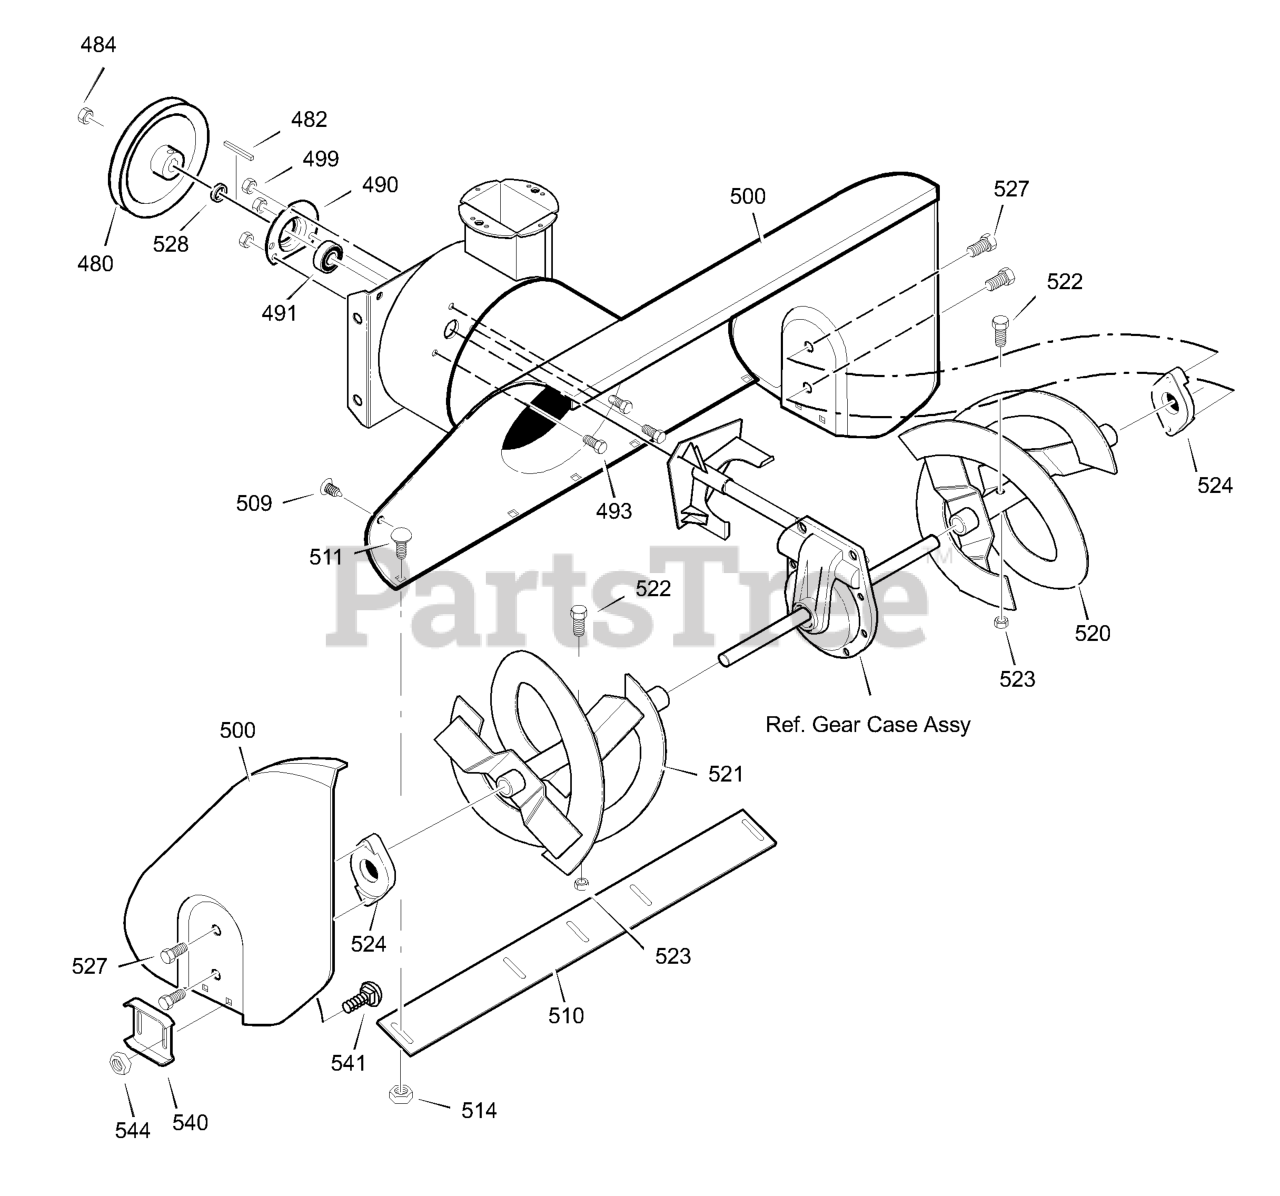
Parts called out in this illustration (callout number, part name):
480	PULLEY, 4L 8.400 O.D.
482	KEY, SQUARE
484	NUT, 1/4-20
485	SPACER, FRICTION PULLEY
490	RETAINER, BALL BRNG
491	BEARING, BALL
493	BOLT, HEX - 0.31-18X0.50
499	NUT, 5/16-18 HEXWDFLLK
500	HOUSING, ASSY
509	PLUG, CHRISTMAS TREE
510	BLADE, SCRAPER
511	BOLT, CARRIAGE
520	AUGER, ASSY, LH
521	AUGER, ASSY, RH
522	BOLT
523	NUT, 5/16-18
524	BEARING,FLANGE
526	NUT, 5/16-18 REGHEX
527	SCREW, 5/16-18 x 0.75
536	BOLT
540	SKID, HEIGHT ADJUST
541	BOLT, 5/16-18 X .75
